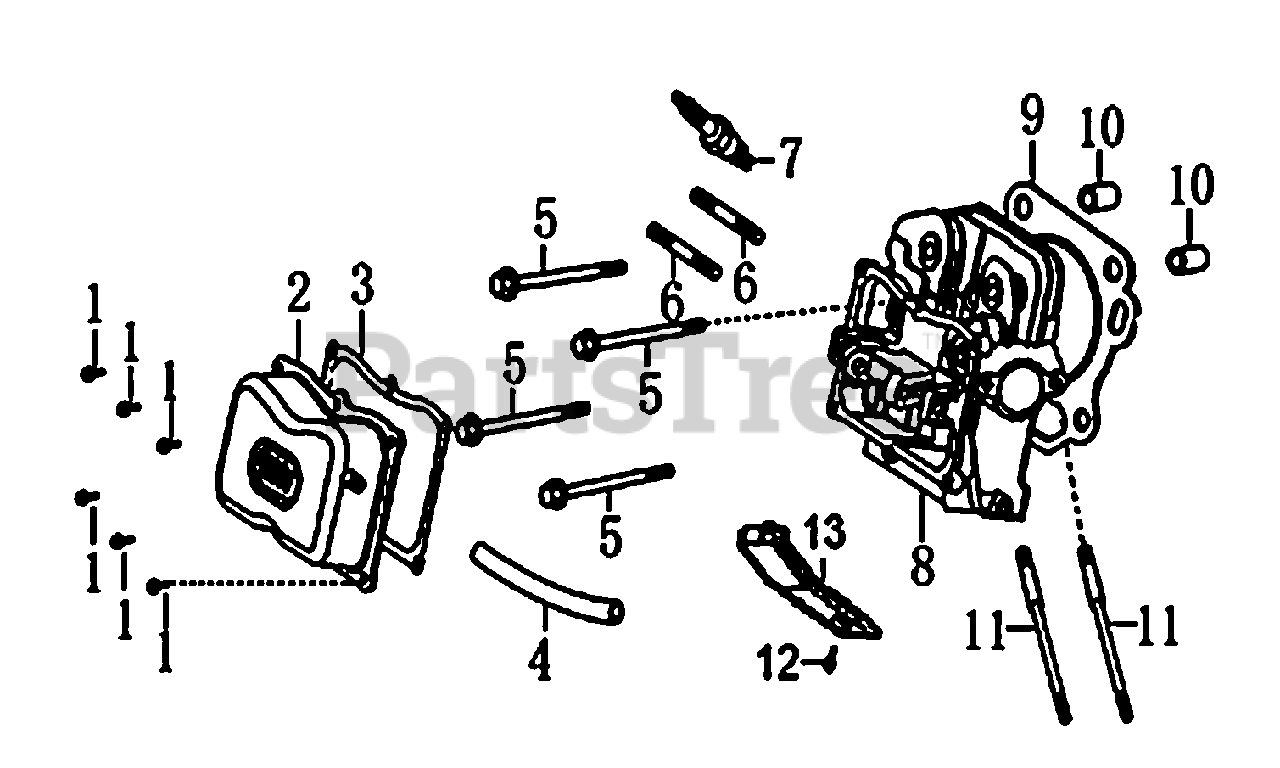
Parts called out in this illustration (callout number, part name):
1	BOLT, FLANGE
2	COVER. HEAD
3	GASKET, HEAD COVER
4	TUBE, BREATHER
5	BOLT, FLANGE, 10X80
6	BOLT, STUD, EXHAUST
7	SPARK PLUG
8	HEAD, CYLINDER
9	GASKET, CYLINDER HEAD
10	PIN, DOWEL
11	BOLT, STUD, INTAKE
12	BOLT, FLANGE M6X12
